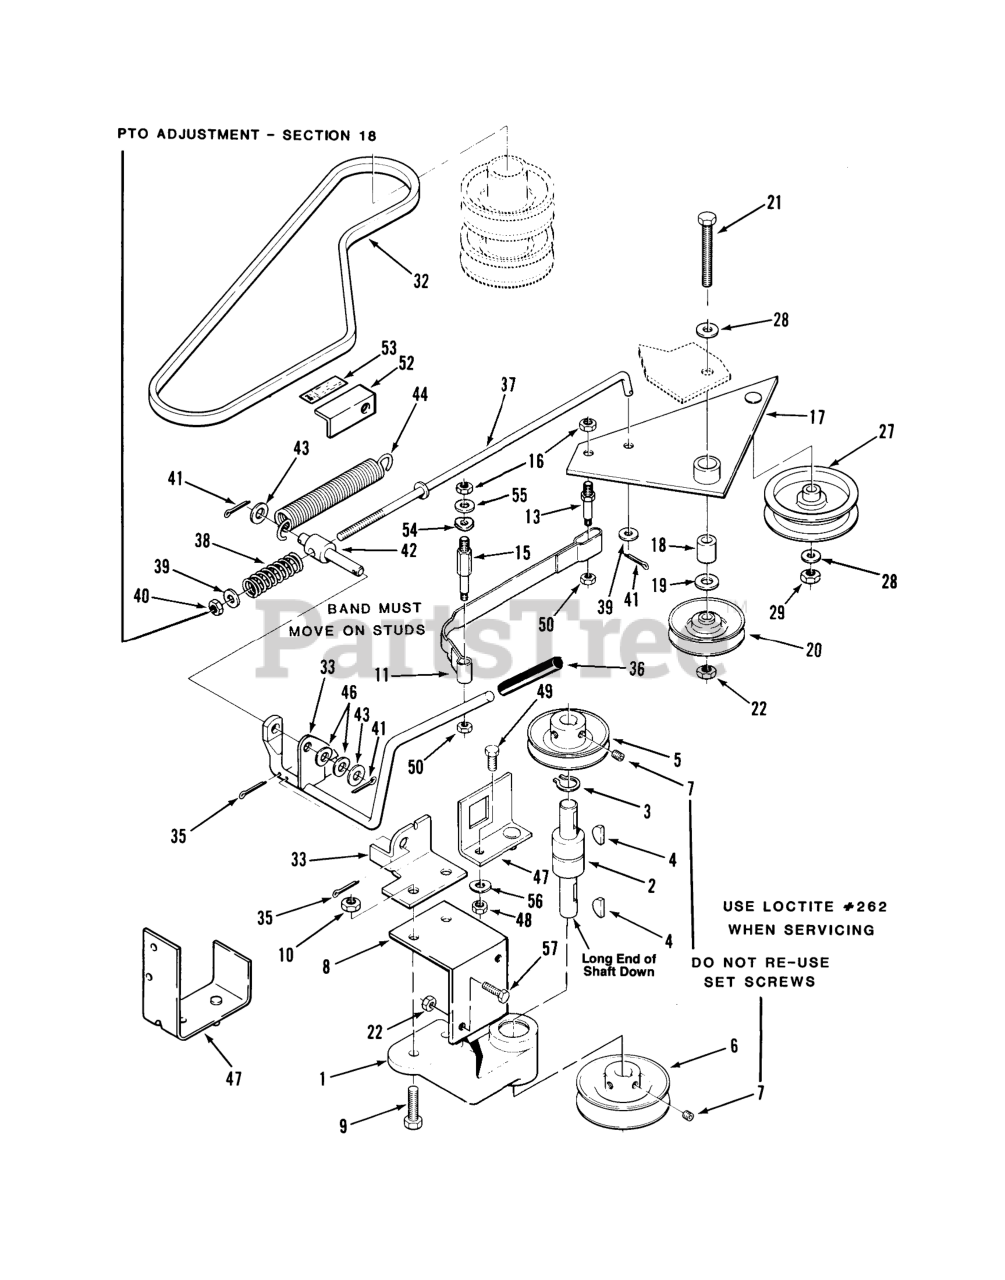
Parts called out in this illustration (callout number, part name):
1	Jack Shaft Housing
2	BEARING-INT SHAFT
3	Snap Ring
4	KEY-WOODRUFF
5	PULLEY CAST IRON
6	PULLEY
7	Set Screw
8	JACKSHAFT-BRACKET R
9	Bolt
10	NUT
11	BAND BRAKE
13	STUD-SHOULDER
15	STUD-SHOULDER LONG
16	Nut
17	PTO Clutch Lever Assy
18	SPACER
19	Washer
20	IDLER PULLEY
21	Bolt
22	NUT
27	Idler Pulley
28	Washer
29	NUT-HEX, JAM
33	ASSY HANDLE PTO CLUT
35	Cotter Pin
36	GRIP
37	ASSY ROD PTO
38	SPRING COMPRESSION
39	WASHER 5/16 SAE
40	Nut
41	Cotter Pin
42	TRUNNION
43	Washer
44	SPRING R
46	WASHER-SPRING
47	ASSY BRACKET SWIT R
48	Nut
49	H H C S
50	Nut
52	PTO INDICATOR BRC R
53	DECAL-PTO BELT ADJ
54	WASHER
55	WASHER 5/16 SAE
57	Bolt
